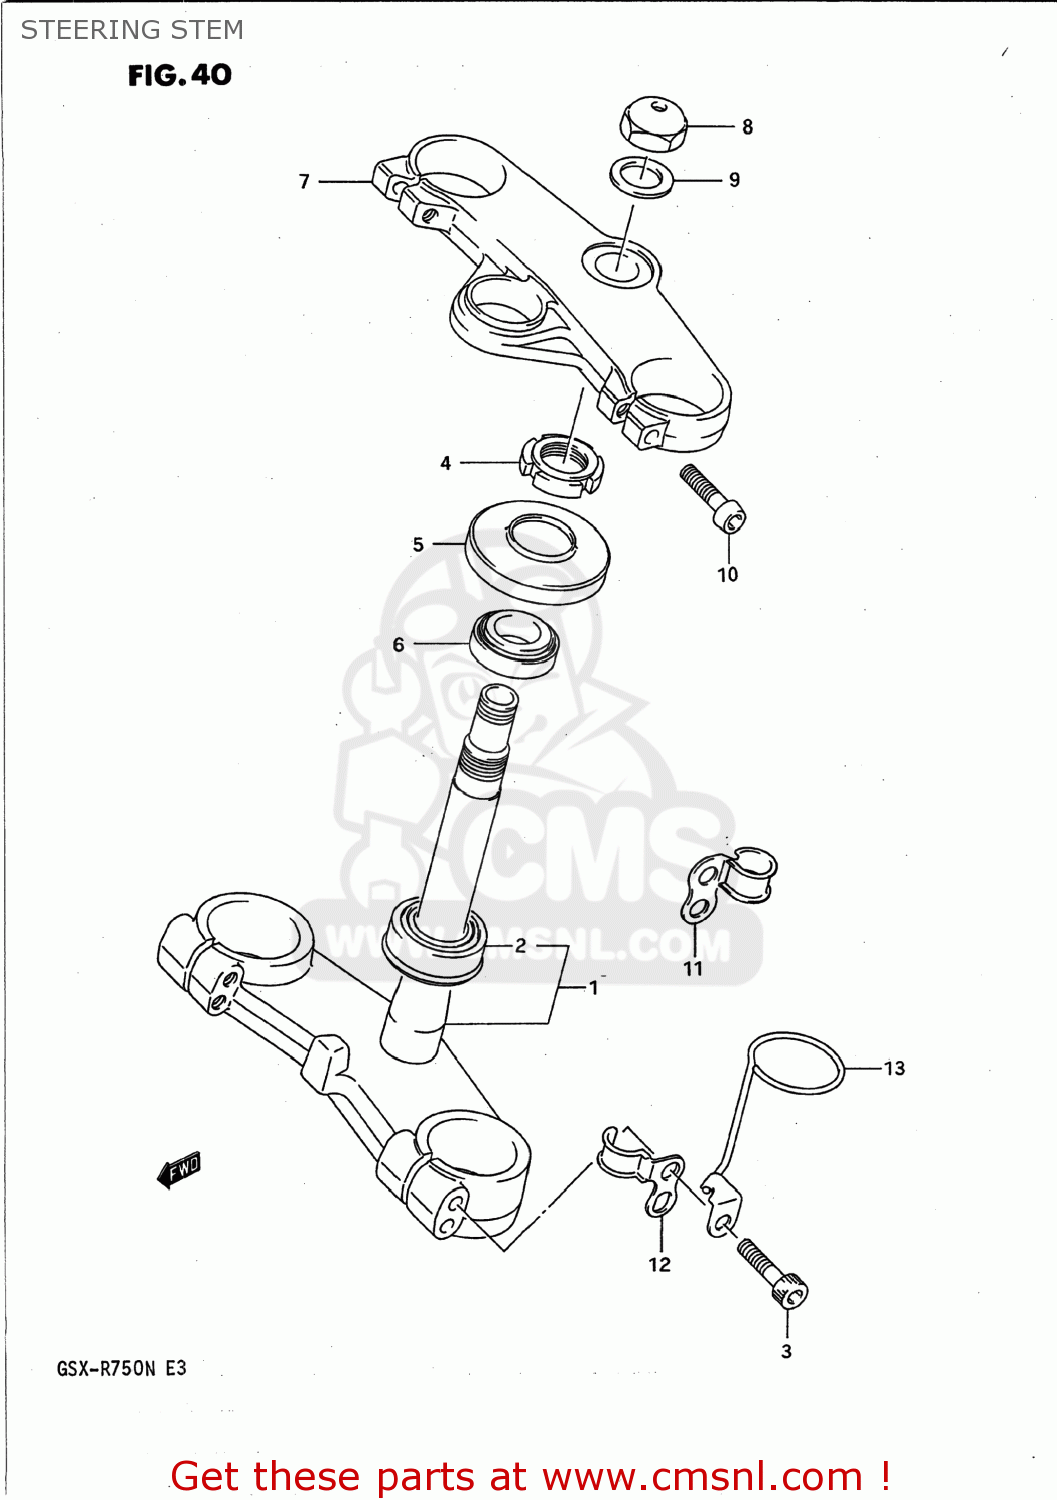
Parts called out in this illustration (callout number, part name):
1	STEM,STEERING
2	BEARING(30X55X17)
3	BOLT 10X45
4	NUT,STEERING STEM(25X44X10)
5	SEAL OIL
6	TAPER,ROLLER BEARING
7	HEAD,STEERING STEM
8	NUT,STEM HEAD
9	WASHER
10	BOLT,UPR
11	GUIDE,SPEEDOMETER CABLE
12	CLAMP,CLUTCH CABLE
13	HOLDER,STEERING DAMPER
